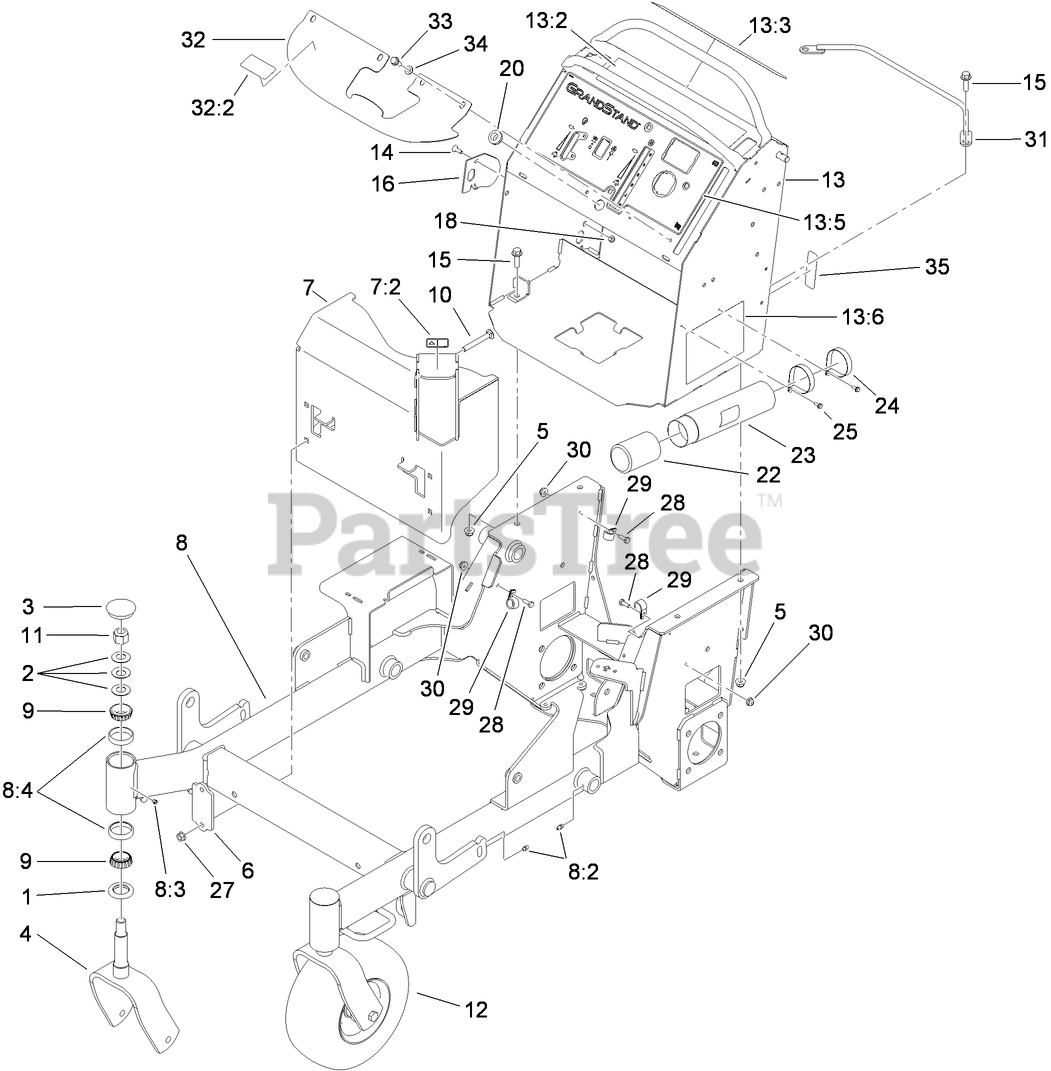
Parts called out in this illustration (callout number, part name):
1	SEAL-GREASE
2	WASHER-BELLVILLE
3	CAP-GREASE
4	FORK-CASTER
5	NUT-HF, NI
6	BRACKET-MOUNTING, GUARD
7	MUFFLER GUARD ASM
7:2	DECAL-WARNING
8	FRAME ASM
8:2	FITTING-GREASE
8:4	CUP-BEARING
9	BEARING-ROLLER, TAPERED
10	SCREW-CARR
11	NUT-LOCK, NI
12	WHEEL/TIRE AND BEARING ASM
13	CONTROL TOWER ASM
13:2	DECAL-OPC
13:3	DECAL-WARNING
13:5	DECAL-PANEL, CONTROL
13:6	DECAL-SERVICE/SPARK ARREST
14	BOLT-CARR
15	SCREW-HHF
16	PLATE-STRIKER
18	NUT-HF
20	GROMMET
22	CAP-HOUSING
23	TUBE-MANUAL
24	CLAMP-R
25	SCREW-TAPTITE
27	NUT-HF
28	SCREW-HH
29	CLAMP-CABLE
30	NUT-HF
31	RETAINER-CABLE
32	COVER-TANK
32:2	DECAL-FILL, FUEL
33	SCREW-HWHTF
34	WASHER-FLAT
35	DECAL-FUSE
